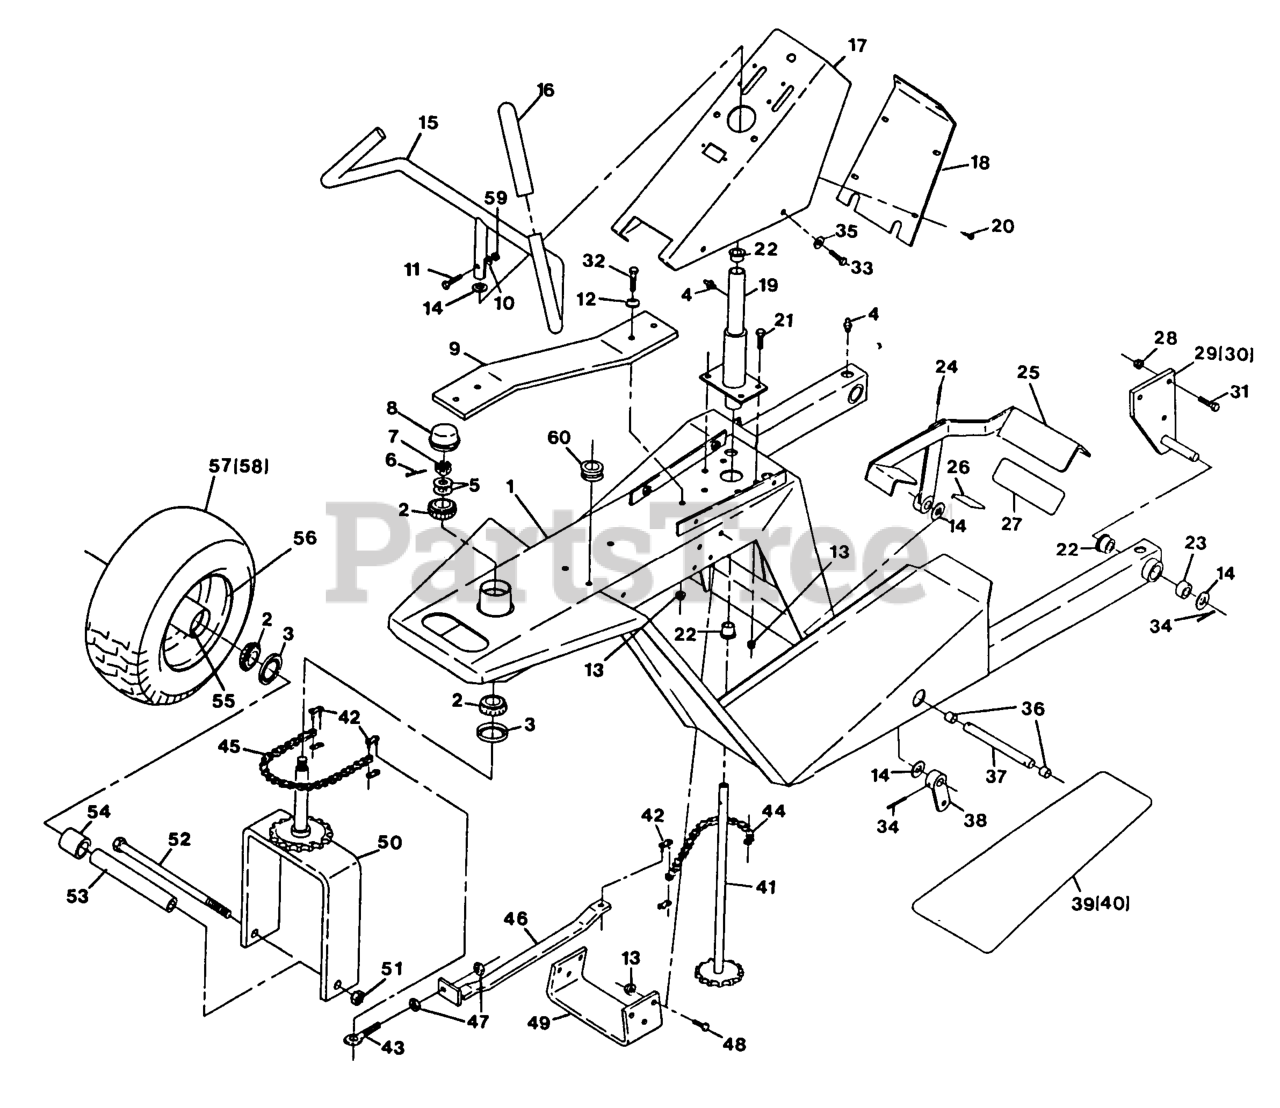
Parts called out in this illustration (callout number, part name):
2	Cone-Bearing Tapered Roller
3	SEAL-GREASE
8	CAP-GREASE
23	SLEEVE,BEARING
24	PIN,ROLL
27	PAD,ANTISKID
29	WLD,BRACKET PIVOT RH
38	WLD,FOOT PEDAL LEVER
39	PAD,ANTISKID RH
43	EYEBOLT, RH
49	STOP,ACTUATOR
52	SCRW,CAP HH
53	BUSHING, WHEEL - PLT
54	SPACER,WHEEL SHORT
55	CUP-BEARING
56	WHEEL 8.00 W/HUB
57	ASM,WHEEL & TIRE
58	TIRE ONLY 8NHS
60	GROMMET
